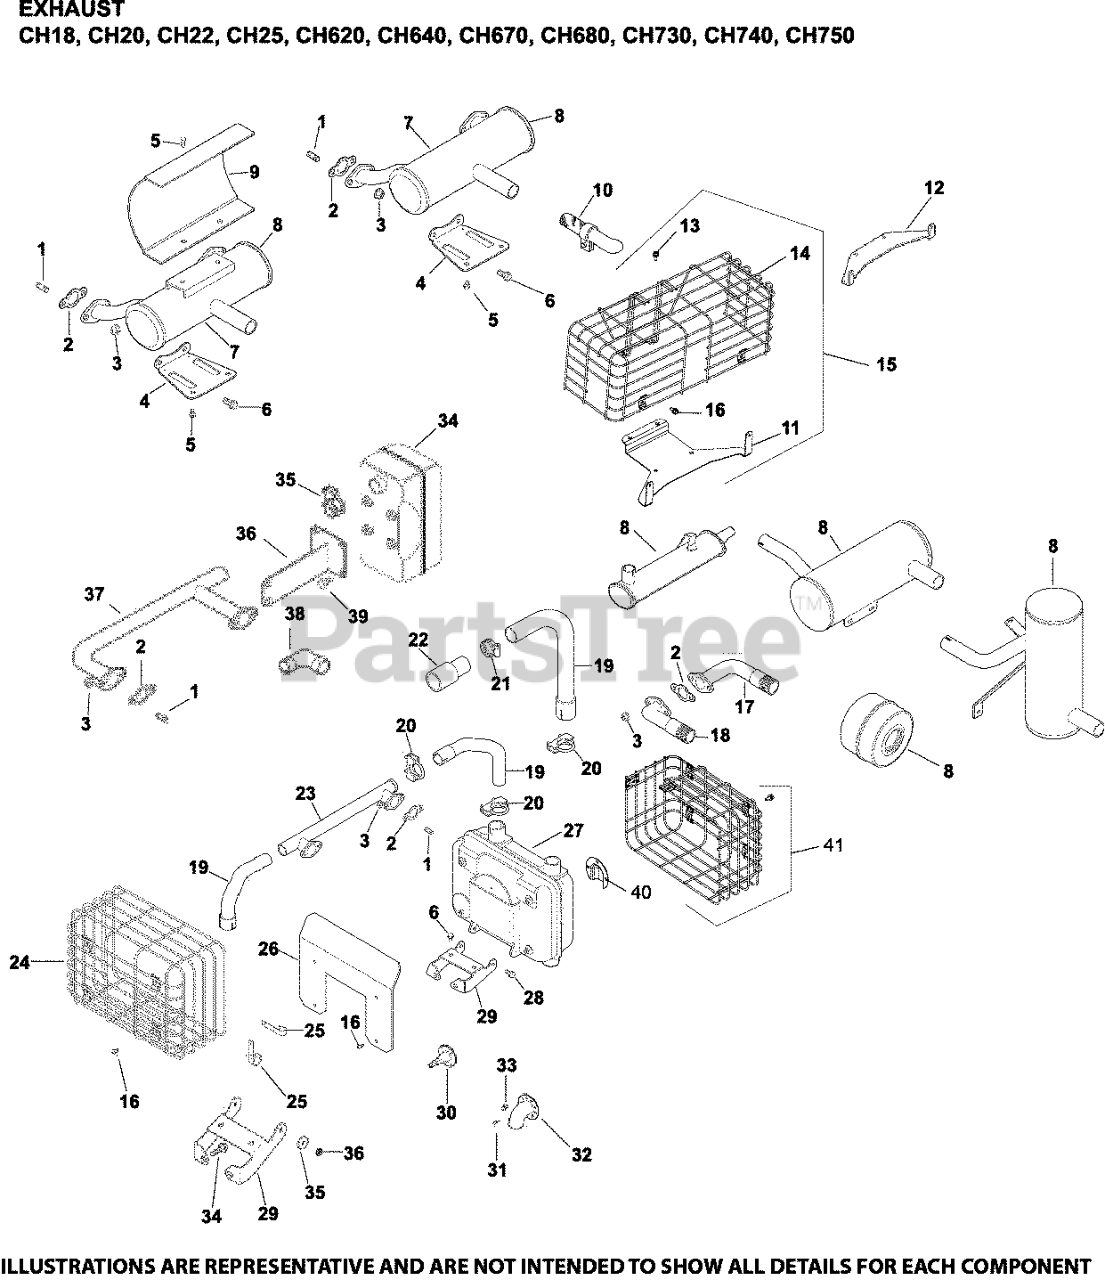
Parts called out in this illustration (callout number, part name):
2	GASKET, EXHAUST
3	NUT, FLG M8X1.25
4	BRACKET, MUFFLER
5	SCREW, FLG M6X1.0X12
6	SCREW, FLG M8X1.25X20
7	MUFFLER KIT, CENTER/STRAIGHT
8	MUFFLER, CENTER/STRAIGHT USE 24 068 131-S
9	SHIELD, ALUM HEAT (LH/CH TWIN)
